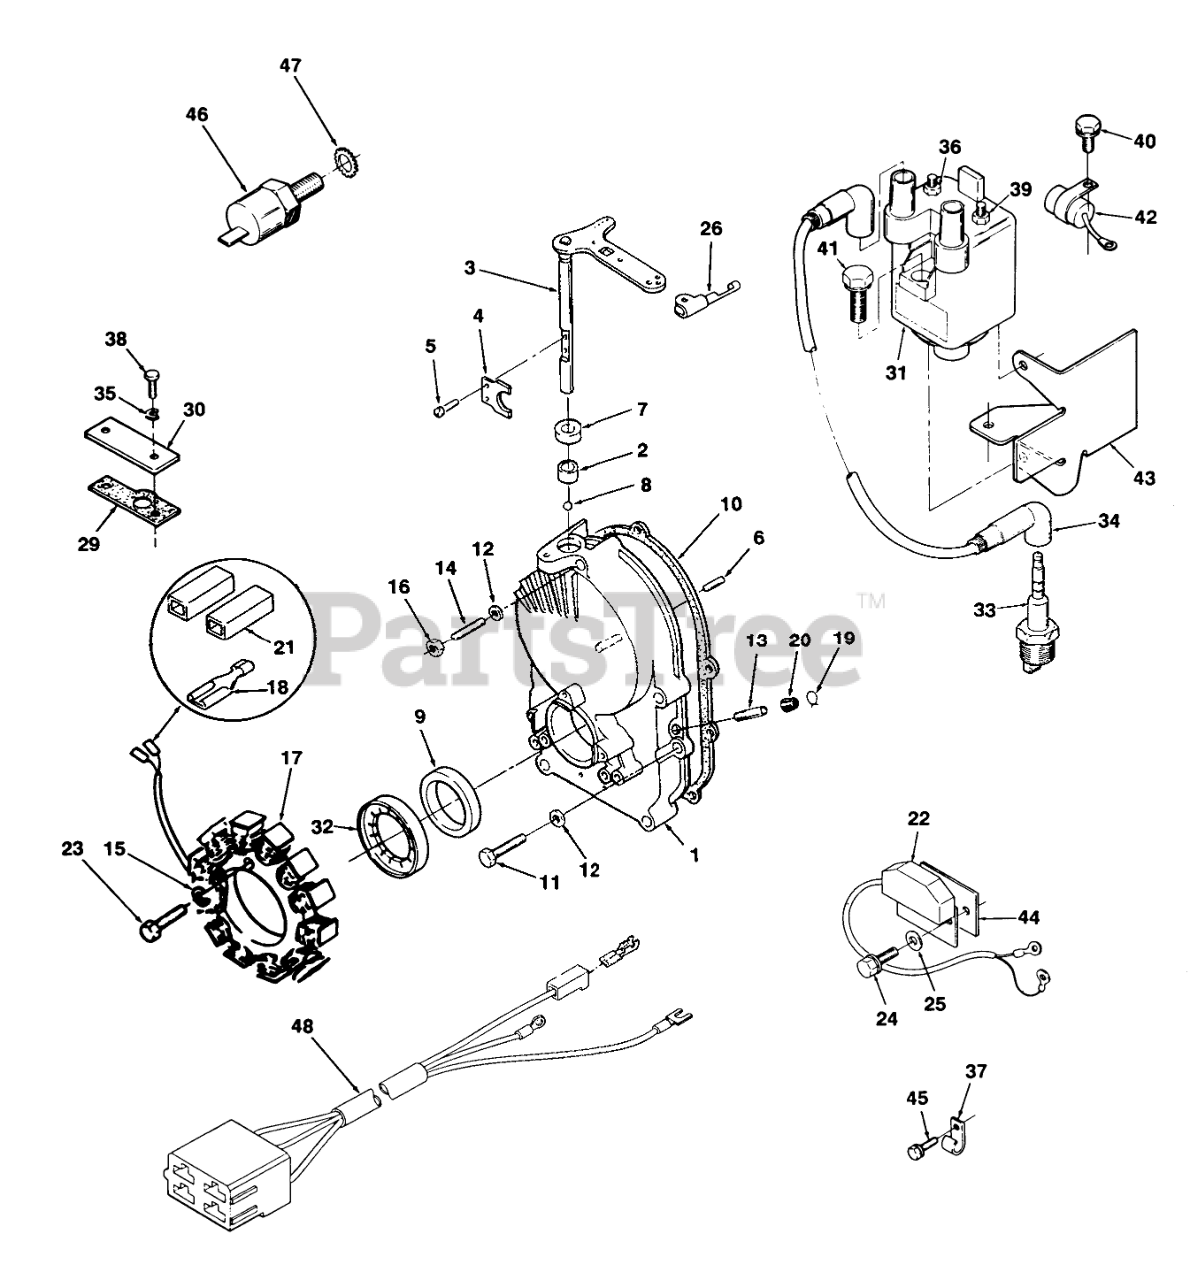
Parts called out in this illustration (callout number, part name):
1	Kit-Gearcase (Incl. Items #2 thru 9)
2	BEARING
3	Governor Shaft & Arm Chromed
5	SCREW-PAN HD
6	PIN-DOWEL
10	Gasket
11	Bolt
12	WASHER
13	TUBE-PORT, VACUUM
14	STUD-GEAR COVER
15	Washer-Lock
16	NUT-GEAR COVER
17	Stator
18	TERMINAL
19	CLAMP
20	CAP-FUEL OUTLET
21	BODY-TERM. CONNECTOR KIT
22	Control-Ignition
23	Screw-HH
24	Bolt
25	WASHER-LOCK
29	Gasket-Plate
30	PLATE-COVER
31	COIL-BATTERY IGNITION
32	ROTOR-IGNITION
33	SPARK PLUG
34	Wire-Plug
35	WASHER-FLAT
36	Nut
37	CLIP-WIRE
38	SCREW - CAP HEX HEAD
39	Nut
40	HEX HD CAPSCREW
41	Bolt
42	CONDENSER
43	BRACKET - COIL MTG
44	Insulator
45	Bolt
46	HIGH TEMPERATURE
47	WASHER-LOCK EXT TO
48	WIRING-HARNESS
